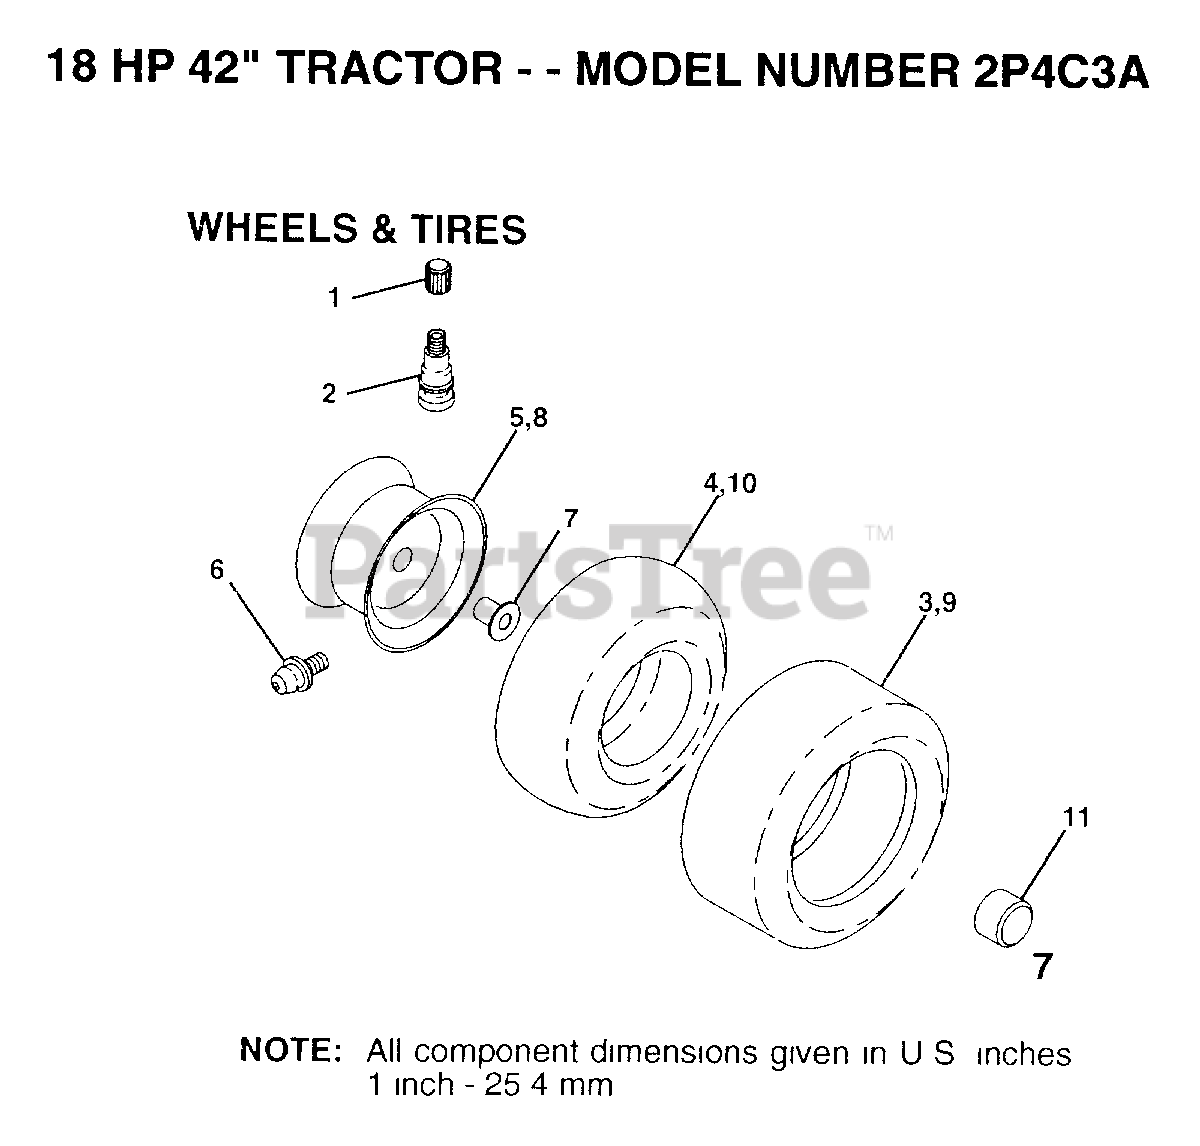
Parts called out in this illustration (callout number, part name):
1	VALVE CAP
2	VALVE STEM LT
3	TUBE.5.3/4.5/6
6	FITTING LT
7	"FLANGE, BEARING"
10	TUBE.18X9.5-8
11	HUB CAP
